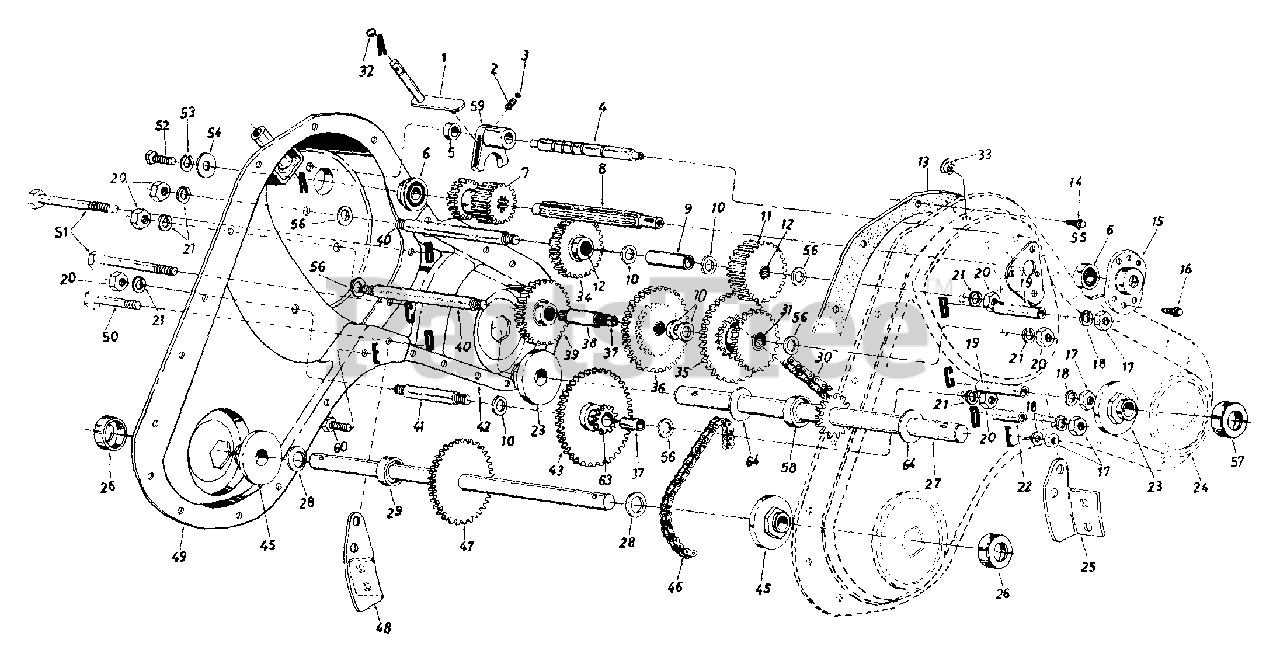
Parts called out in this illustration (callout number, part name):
1	Shifting Bracket Ass'y.
2	Compression Spring .50" Lg.
3	Ball Detent .250" Dia.
4	Detent Shaft 1/2" Dia.
5	Spacer .505" I.D. x .88" O.D.
6	Ball Brg. .62" I.D. x 1.38"
7	Spur Gear 16T (Input)
8	Input Spline Shaft 7/8"
9	Spacer .657" I.D. x 2.85" Lg.
10	Fl-Wash. .640" I.D. x 1.24"
11	Spur Gear 30T 7/8" I.D.
12	Needle Bearing 5/8" I.D.
13	Gasket - Trans. Hsg.
14	Hex S-Tap Scr. 1/4-20 x .5"
15	1-3/8" Dia. Bearing Housing
16	Hex TT-Tap Scr. 1/4-20 x .75"
17	Hex Nut 5/16-18 Thd.
18	L-Wash. 5/16" I.D.
19	Spacer 1.56" Lg.
20	Hex Nut 7/16-20 Thd.
21	Bell-Wash. .45" I.D. x 1.0"
22	Spacer 1.015" Lg.
23	Tine Shaft Brg. 1.002 x 2.50
24	Trans. Housing Ass'y. - L.H.
27	Tine Shaft Ass'y. 1" O.D.
28	Fl-Wash. .76" I.D. x 1.5" O.D.
29	Spacer .75" I.D. x .50" Lg.
30	Chain #50 5/8 Pitch x 52 Links - Endless
31	Needle Bearing 5/8" I.D.
32	Snap Ring
33	Taper Cap Plug
34	Spur Gear 30T 12/16" I.D.
35	30/44T Gear Ass'y. Comp.
36	Spur Gear 44T
37	Sleeve Bearing
38	Gear Hub 3/4" I.D. x 3" Lg.
39	Spur Gear 30T 1.0" I.D. x 1/2" W
40	Jack Shaft 5/8" Dia. x 5"
41	Jack Shaft 5/8" Dia. x 2.38"
42	Trans. Housing Ass'y. - R.H.
43	Spur Gear 55T
45	Wheel Brg. .752" x 2.5"
46	#420 Chain 1/2 Pitch x 50 Links - Endless
47	Wheel Shaft Ass'y. 15.6"
51	Hex Bolt 5/16-18 x 2.5"
52	Hex Bolt 1/4-20 x .62" Lg.
53	L-Wash. 3/8" I.D.
54	Fl-Wash. 1/4" I.D. x .93" O.D.
55	Gear Positioner Bracket
56	Fl-Wash. 7/16" I.D. x 1-3/8"
57	Dust Cover Ass'y. 1" Shaft
58	Spacer 1" I.D. x 2" O.D.
59	Shifting Fork
60	Hex Bolt 5/16-18 x .75" Lg.
63	10T Sprocket Ass'y.
64	Thrust Wash. 1.03" I.D. x 1.62" O.D.
